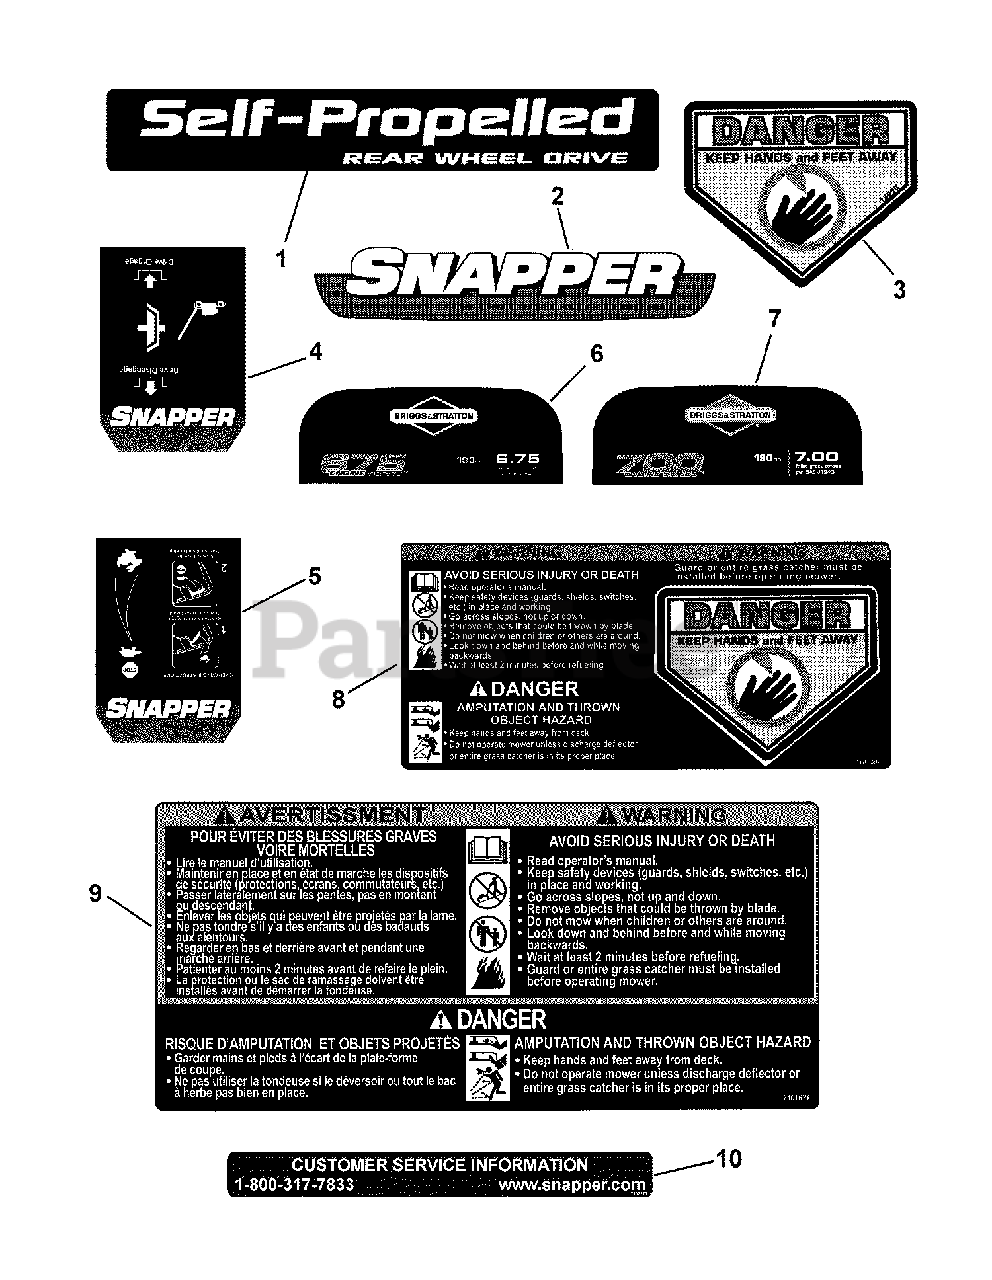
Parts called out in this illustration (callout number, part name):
1	DECAL, Front Cover, 21 RD, Snapper
2	DECAL, Briggs Engine, Snapper
3	DECAL, Danger, Cut Finger
4	DECAL, Control Head, VS, Snapper, FC
5	DECAL, Control Head, VS, Snapper
6	DECAL, Engine, TP, 675 Series
7	DECAL, B&S Engine, 700 Series
8	DECAL, Warning, Rear Discharge Door
9	DECAL, WB Safety, French/English
10	DECAL, Customer Service
